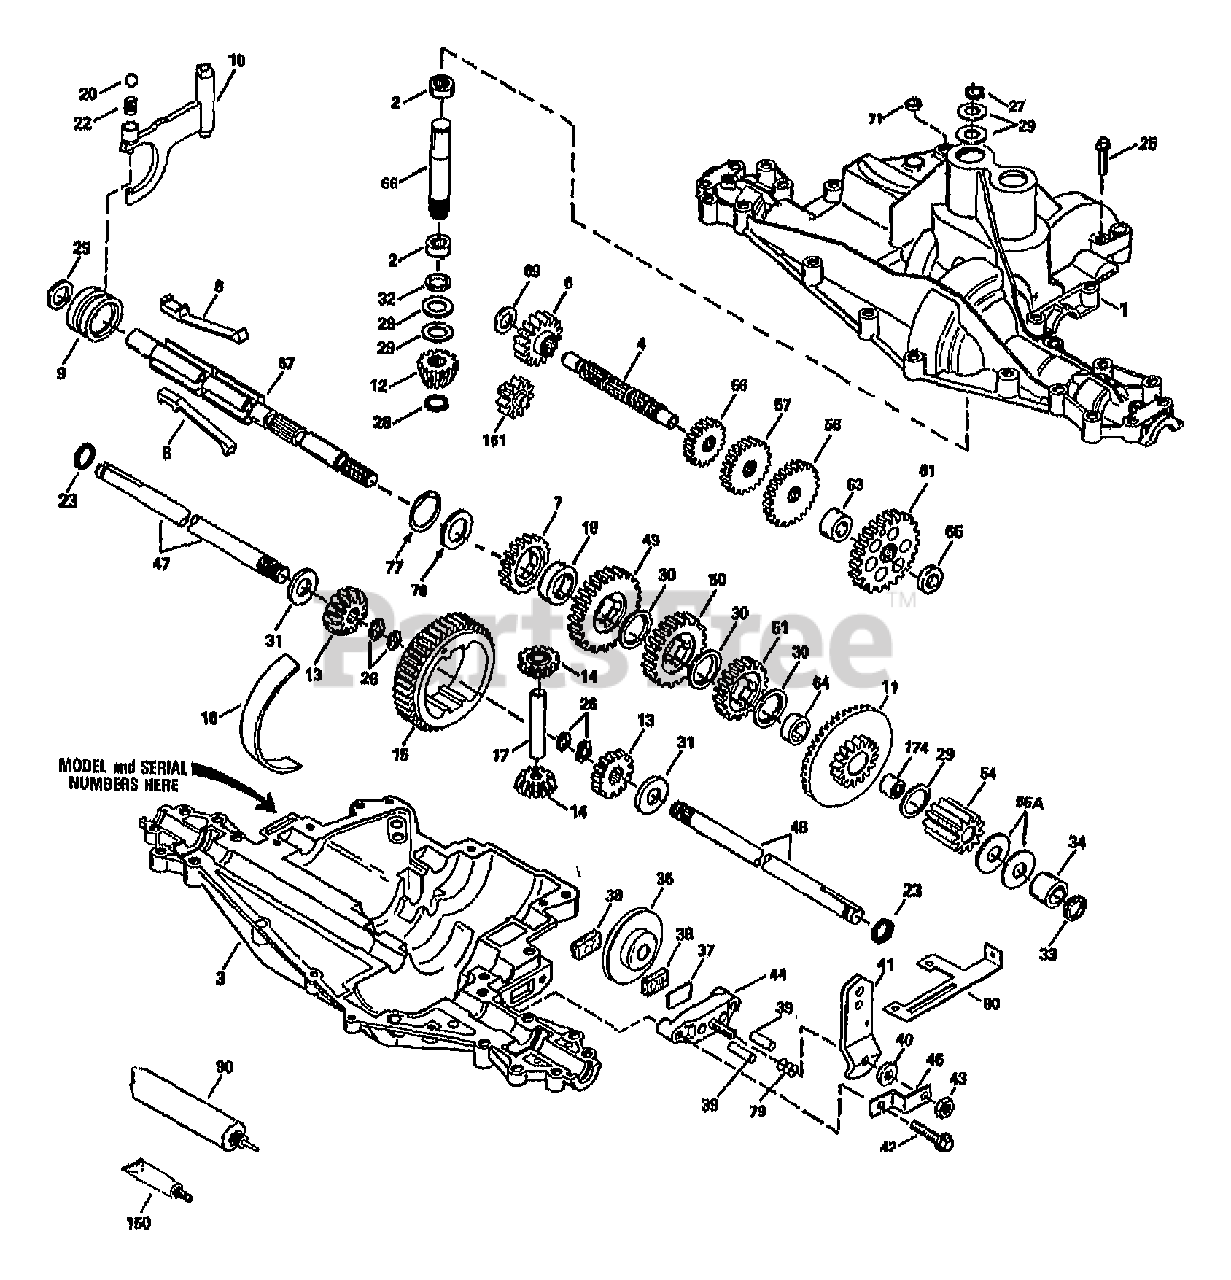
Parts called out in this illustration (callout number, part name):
1	TRANSAXLE COVER
2	NEEDLE BEARING
3	TRANSAXLE COVER
4	COUNTERSHAFT
6	SPUR GEAR (16 TEETH)
7	SPUR GEAR (22 TEETH)
8	SHIFT KEY
9	SHIFT COLLAR
10	SHIFT ROD & FORK
11	BEVEL GEAR & BEARING (INCL. 174)
12	BEVEL PINION (14 TEETH )
13	BEVEL GEAR (16 TEETH )
14	DIFFERENTIAL PINION
15	RING GEAR
16	BEARING STRIP
17	DRIVE PIN
18	NEUTRAL SPACER
20	STEEL BALL, 5/16" DIA.
22	SPRING
23	SEAL RING
25	SCREW, 1/4-20 X 1-1/4
26	RETAINING RING
27	RETAINING RING
28	RETAINING RING
29	WASHER
30	WASHER
32	"O" RING
33	"O" RING
36	BRAKE DISK
37	BRAKE PAD PLATE
38	BRAKE PAD (PKG. OF 2)
39	DOWEL PIN
41	BRAKE LEVER
42	SCREW, 1/4-20 X 1-1/4
43	LOCKNUT, 5/16-24
44	BRAKE PAD HOLDER
46	BRAKE LEVER BRACKET
47	AXLE (14-13/16" LONG)
48	AXLE (9-5/8" LONG)
49	SPUR GEAR (30 TEETH)
50	SPUR GEAR (25 TEETH)
51	SPUR GEAR (22 TEETH)
54	SPUR GEAR (11 TEETH)
56	SPUR GEAR (20 TEETH)
57	SPUR GEAR (25 TEETH)
58	SPUR GEAR (28 TEETH)
61	SPUR GEAR (34 TEETH)
64	OUTPUT SHAFT SPACER
66	INPUT SHAFT
67	SHIFTER & BRAKE SHAFT
71	SQUARE CUT RING
77	INVERTED RETAINING RING (PKG. OF 2)
80	BRAKE BRACKET
90	GREASE SPECIFICATION
150	GASKET ELIMINATOR (LOCTITE #515)
161	REVERSE IDLER
174	NEEDLE BEARING
